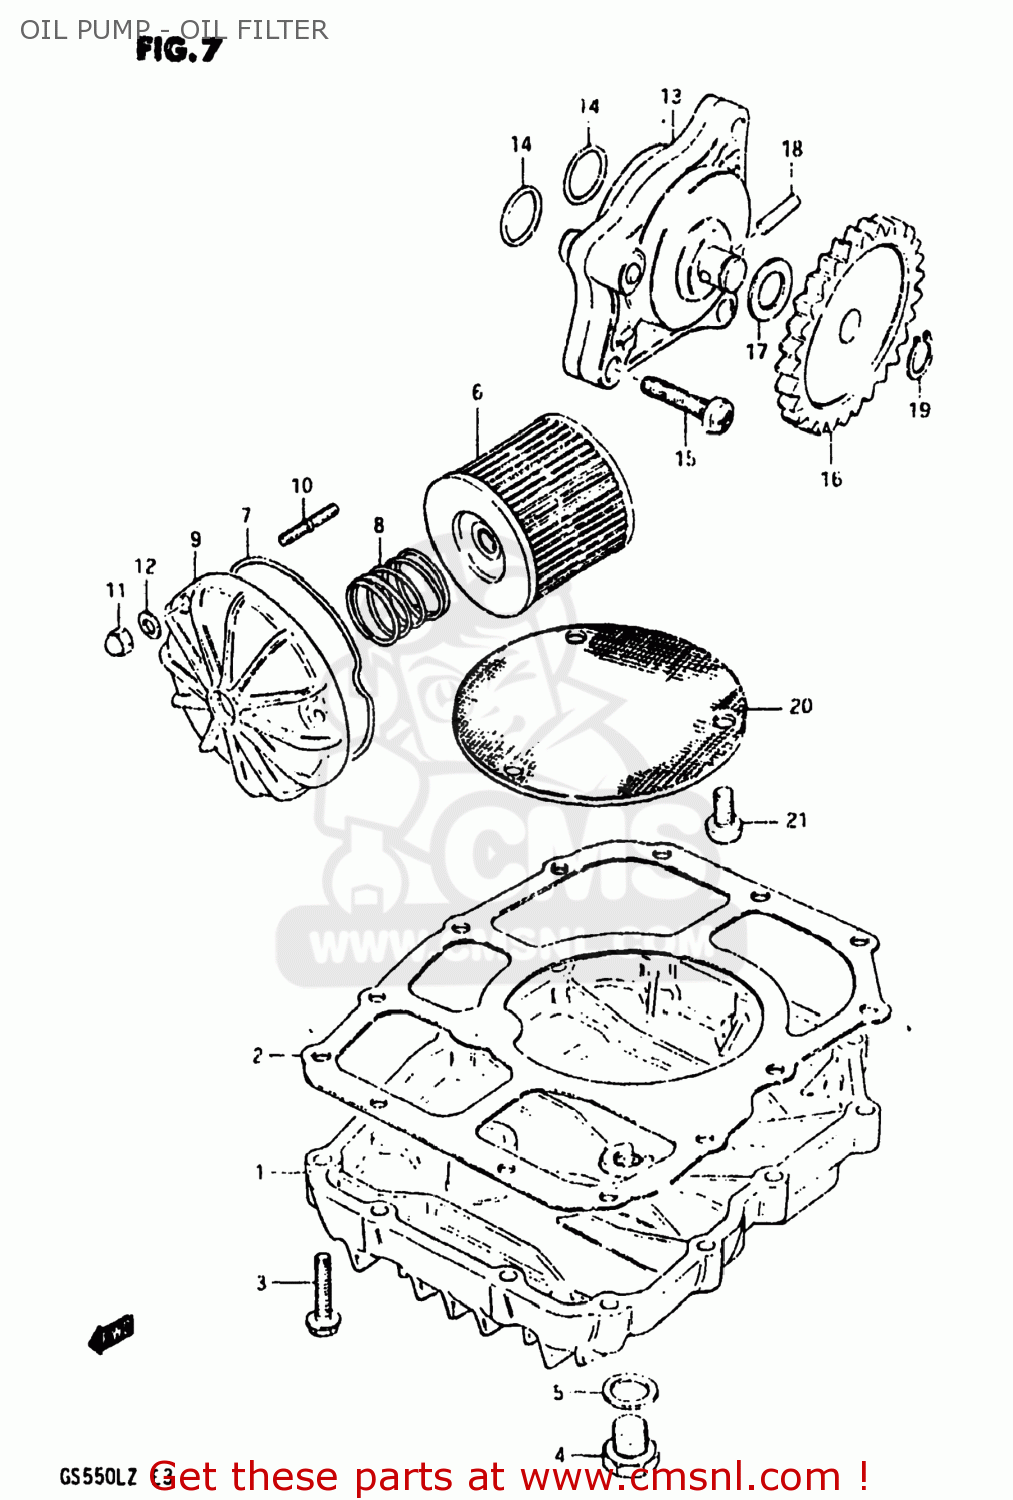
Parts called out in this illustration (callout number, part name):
1	PAN,OIL
2	GASKET,OIL PAN (MCA)
3	BOLT
4	PLUG
5	GASKET(14X19.2X2) (NAS)
6	FILTER ASSY,ENGINE OIL
7	O RING,OIL FILTER CHAMBER CAP
8	SPRING
9	CAP,ENGINE OIL FILTER
10	STUD 6X20
11	NUT
12	WASHER
13	PUMP ASSEMBLY,ENGINE OIL
14	O RING(D:1.9,ID:13)
15	SCREW
16	GEAR,OIL PUMP DRIVEN
17	SHIM
18	PIN(4X15.8)
19	CIRCLIP
20	STRAINER,ENGINE OIL
21	SCREW 6X12
